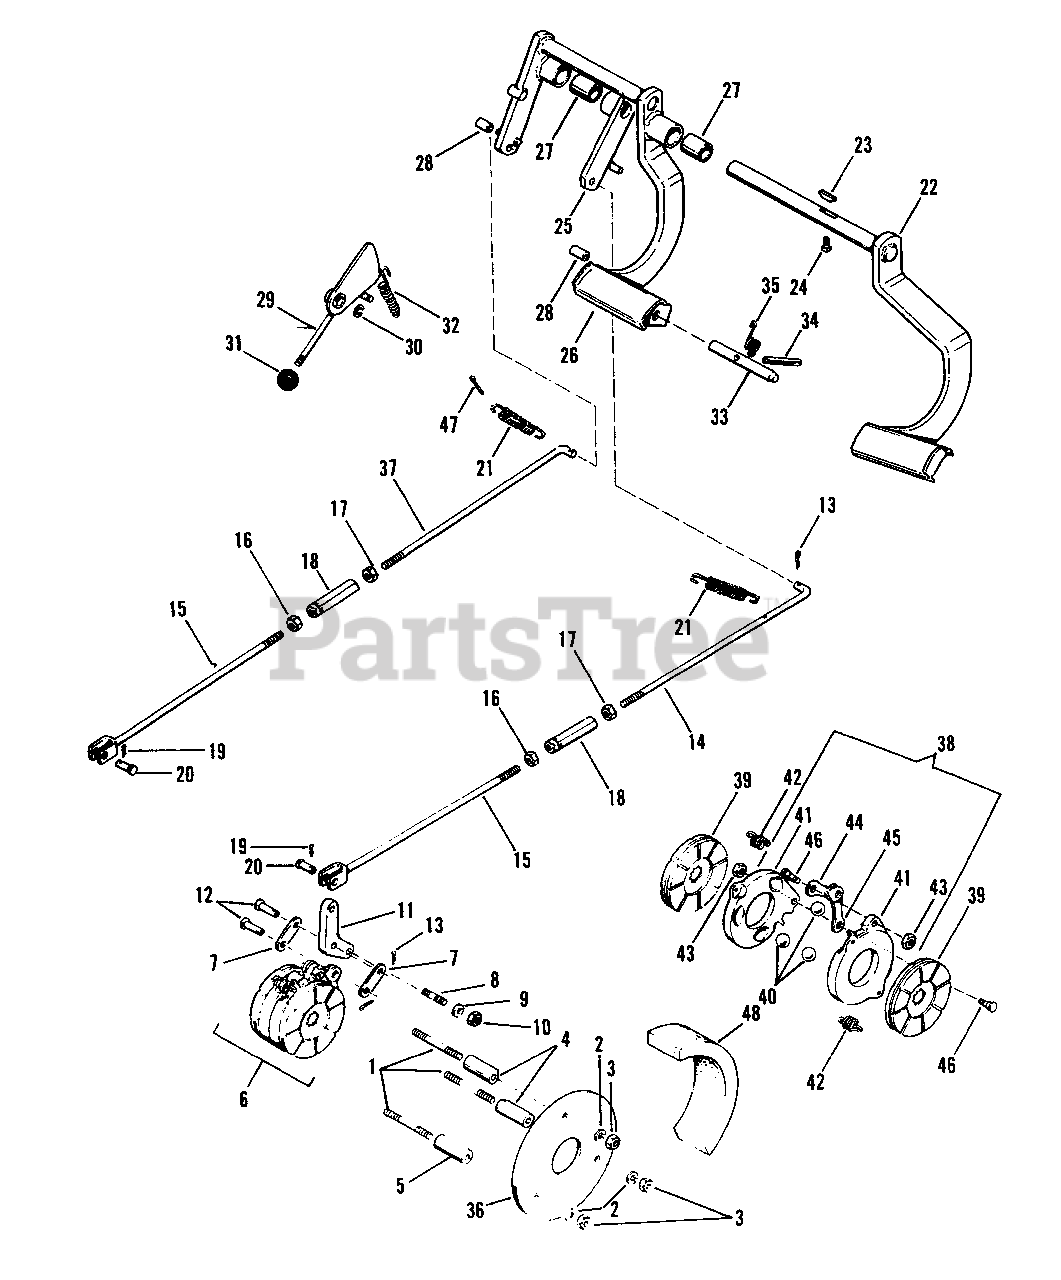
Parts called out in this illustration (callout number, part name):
2	Lock Washer, 3/8"
3	Hex Nut, 3/8"-16
6	Brake Assembly
7	Link Plate
9	Plain Washer, 5/16"
10	Hex Nut, Full, Lock, 3/8"-16
11	Brake Lever
13	Cotter Pin, 3/32" x 3/4' lg.
14	Front Brake Rod R.H.
15	Rear Brake Rod Assy.
16	Hex Nut, Jam, 3/8"-24 R.H.
17	Hex Nut, Jam, 3/8"-24 L.H.
18	Turnbuckle
19	Cotter Pin
21	Spring
22	Brake Lever Assembly, R.H.
24	Set Screw, 5/16"-18 x 3/8" lg.
25	Brake Rod Anchor Assy.
26	Brake Lever Assy., L.H.
27	Bearing Sleeve
29	Cam Assembly
30	Retaining Ring
33	Pedal Lock Pin
34	Roll Pin
36	Shim Plate
37	Front Brake Rod L.H.
38	Actuating Disc Assy.
39	Middle Disc Assembly
41	Acutating Disc.
43	Hex Nut, Jam
44	Link Assembly (Yoke)
45	Acutating Link
47	Cotter Pin, 5/32" x 1" lg.
